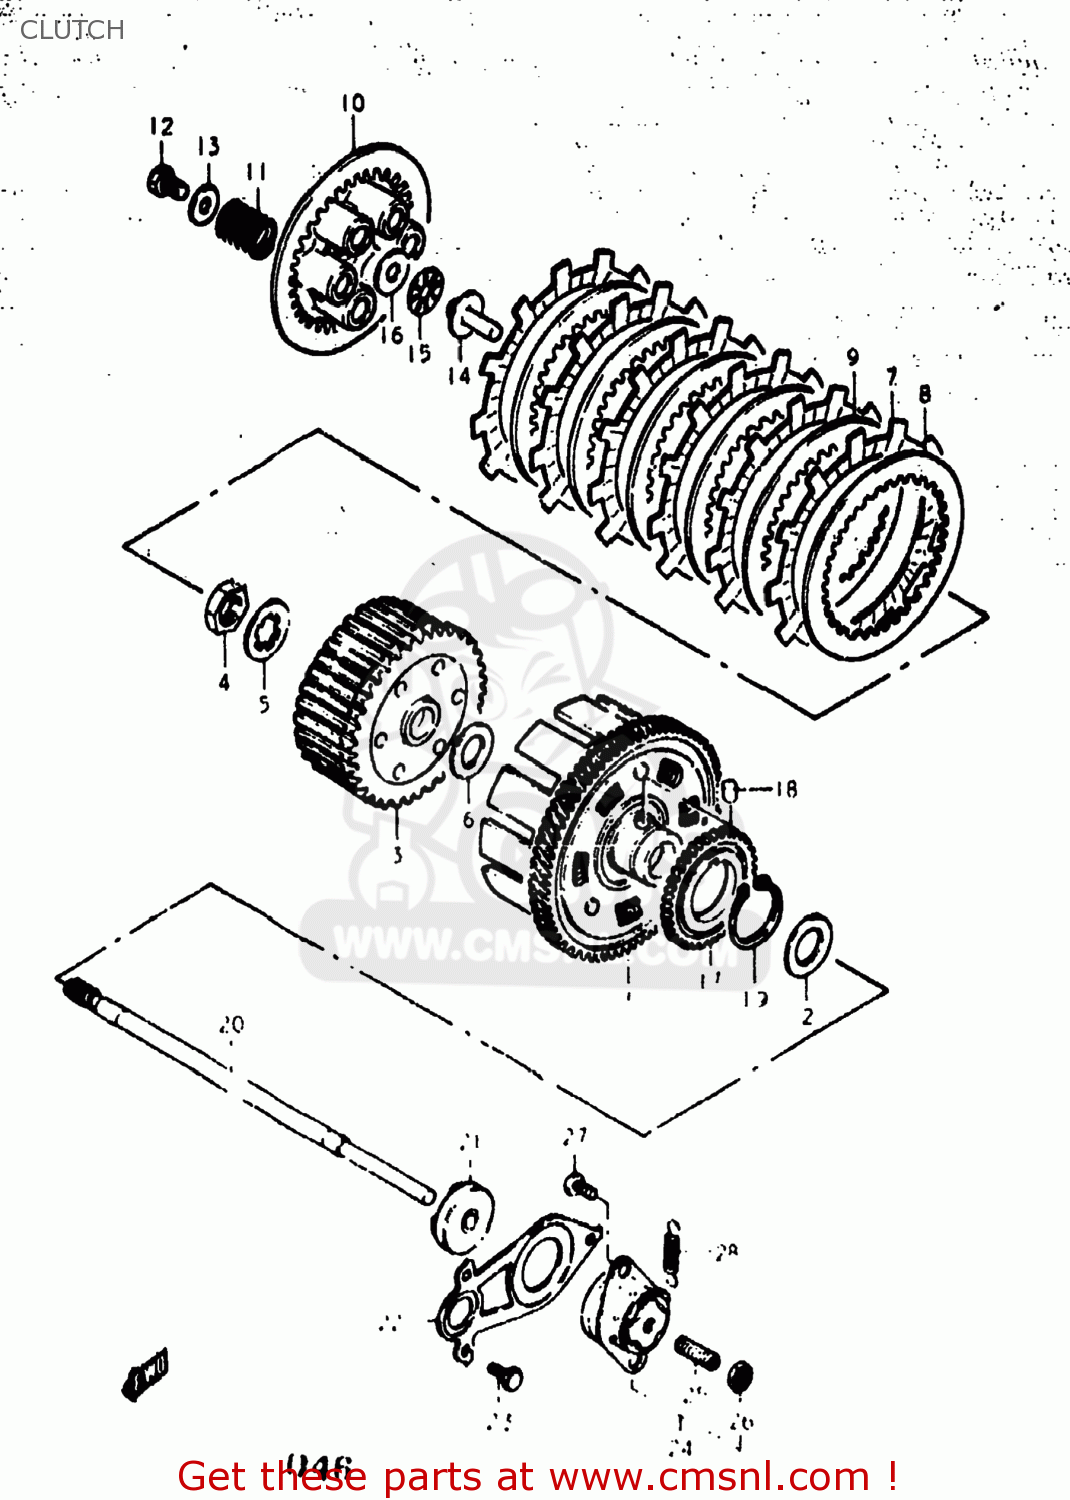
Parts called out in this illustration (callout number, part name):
1	GEAR ASSEMBLY,PRIMARY DRIVE
2	WASHER
3	HUB,CLUTCH SLEEVE
4	NUT (20MM)
5	WASHER,LOCK
6	WASHER(20X38X2)
7	PLATE,CLUTCH DRIVE (NAS)
8	PLATE,CLUTCH DRIVEN(T:2.0) (NAS)
9	PLATE,CLUTCH DRIVEN (NAS)
10	DISC,CLUTCH PRESSURE
11	SPRING
12	BOLT
13	WASHER
14	PIECE,CLUTCH PUSH
15	BEARING(15X28X2)
16	WASHER
17	GEAR,OIL PUMP DRIVE
18	PIN(6X6)
19	CIRCLIP
20	ROD,CLUTCH PUSH
21	OIL SEAL
22	RETAINER,CL PUSH ROD OIL SEAL
23	BOLT
24	SCREW ASSEMBLY,CLUTCH RELEASE
25	SCREW
26	NUT
27	SCREW 6X12
28	SPRING
